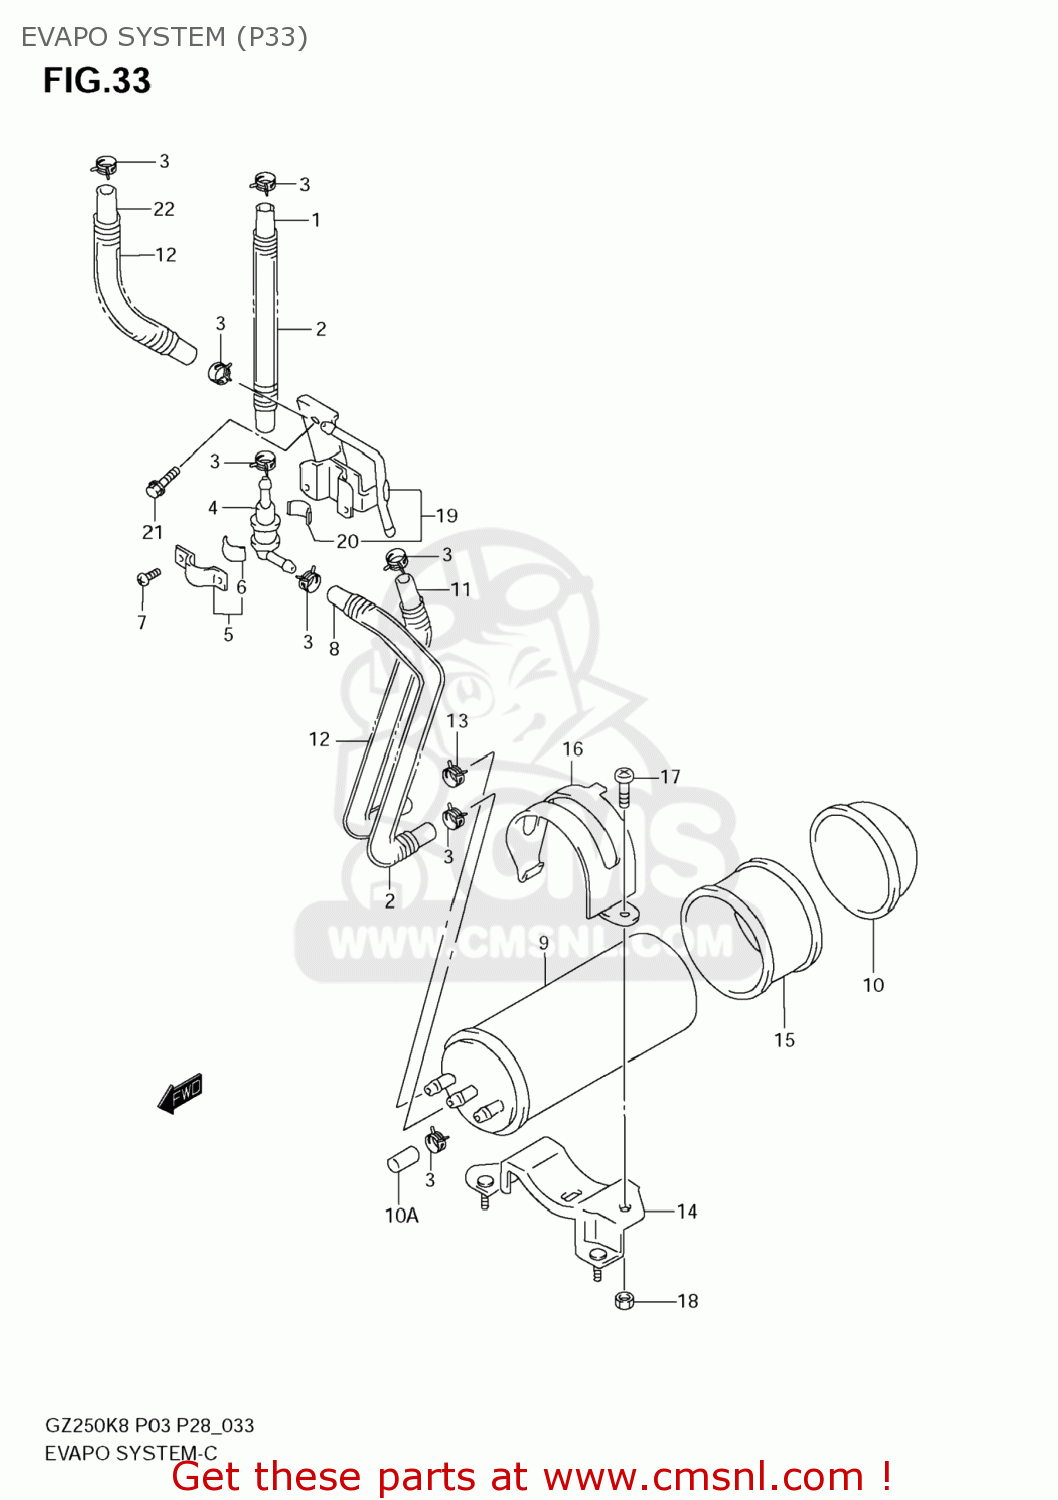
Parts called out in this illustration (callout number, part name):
1	HOSE,TANK & BREATHER VALVE
2	SPRING
3	CLIP
4	VALVE,FUEL TANK BREATHER
5	PLATE,FUEL TANK BREATHER NO.2
6	CUSHION
7	SCREW
8	HOSE,BREATHER VALVE & CANISTER
9	CANISTER ASSY,CHARCOAL
10	CAP,CANISTER
10A	CAP,OD:11.5
11	HOSE,CSTR & CARB NO.1
12	SPRING
13	CLIP
14	BRACKET,CANISTER
15	CUSHION,CANISTER
16	HOLDER,CANISTER
17	SCREW
18	NUT
19	BRACKET,FUEL TANK BREATHER
20	CUSHION
21	BOLT
22	HOSE(5.4X11.4X600)
